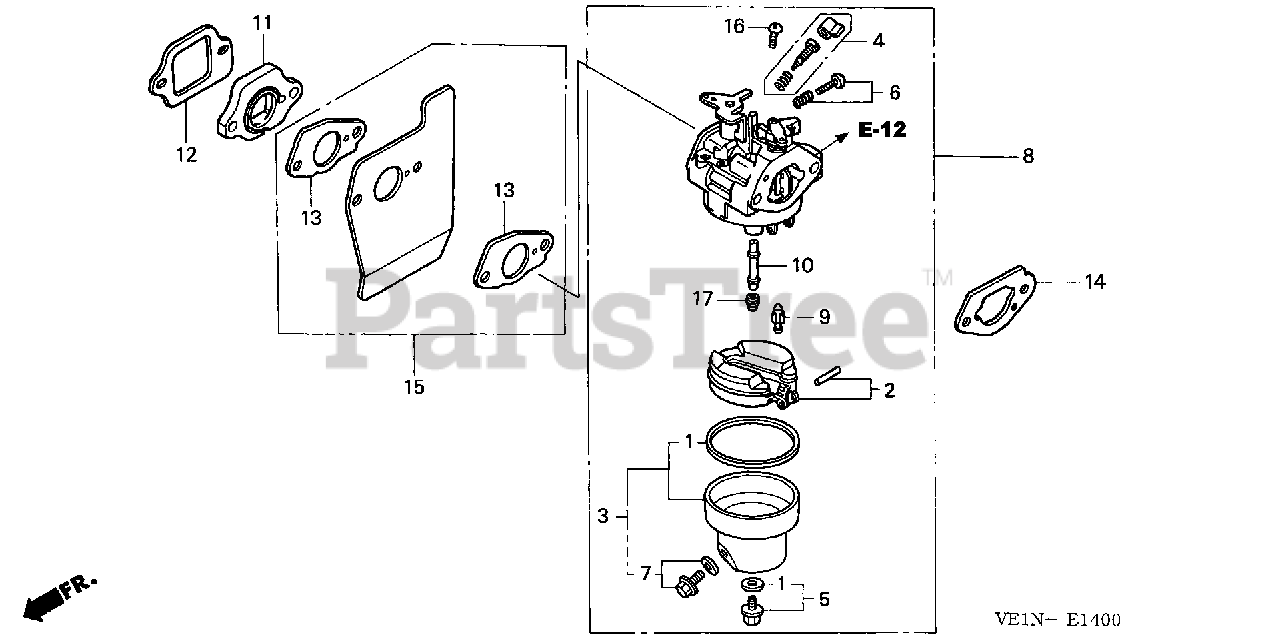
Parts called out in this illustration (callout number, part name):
1	GASKET SET
3	CHAMBER SET, FLOAT
5	SCREW SET
6	SCREW SET (THROTTLE STOP)
7	SCREW SET, DRAIN
8	CARBURETOR ASSY. (BB62J A)
8	CARBURETOR ASSY. (BB62J B)
8	CARBURETOR ASSY. (BB65B A)
8	CARBURETOR ASSY. (BB65B B)
8	CARBURETOR ASSY. (BB65B C)
9	VALVE, FLOAT
10	NOZZLE, MAIN
11	INSULATOR, CARBURETOR
12	GASKET, INSULATOR
13	GASKET, CARBURETOR
14	GASKET, CARBURETOR
15	GUIDE, AIR
16	SCREW, PAN (5X6)
17	JET, MAIN (#65)
17	JET, MAIN (#68)
17	JET, MAIN (#70)
